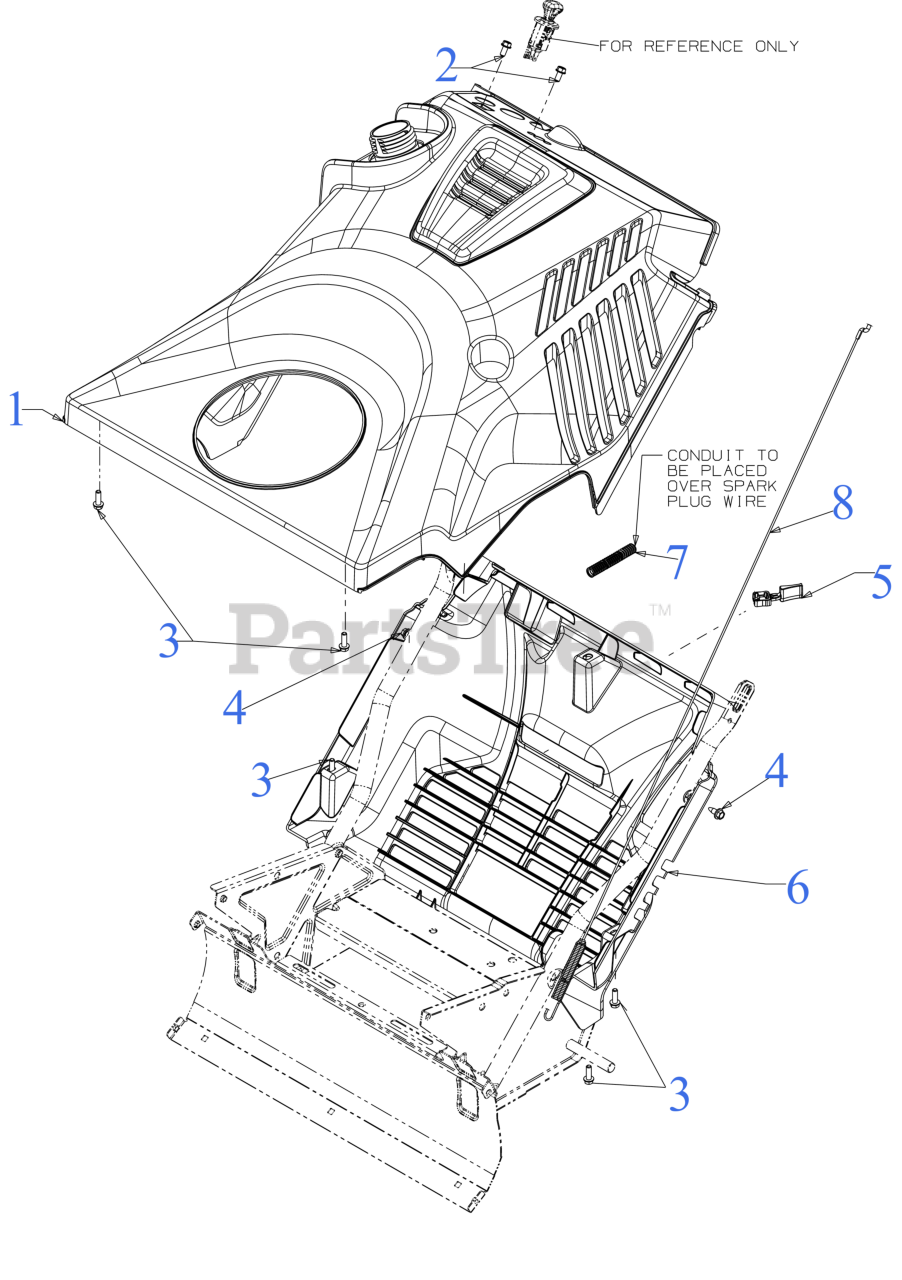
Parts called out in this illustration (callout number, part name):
1	COVER ASSEMBLY (YELLOW)
2	HEX SCREW 1/4-15 x .50
3	SCREW 1/4-15 x .750
4	SCREW 1/4-20X.625
5	CHOKE EXTENION LEVER
6	BOTTOM COVER
7	CONVOLUTED CONDUIT
8	AUGER CLUTCH CABLE 37.05"
